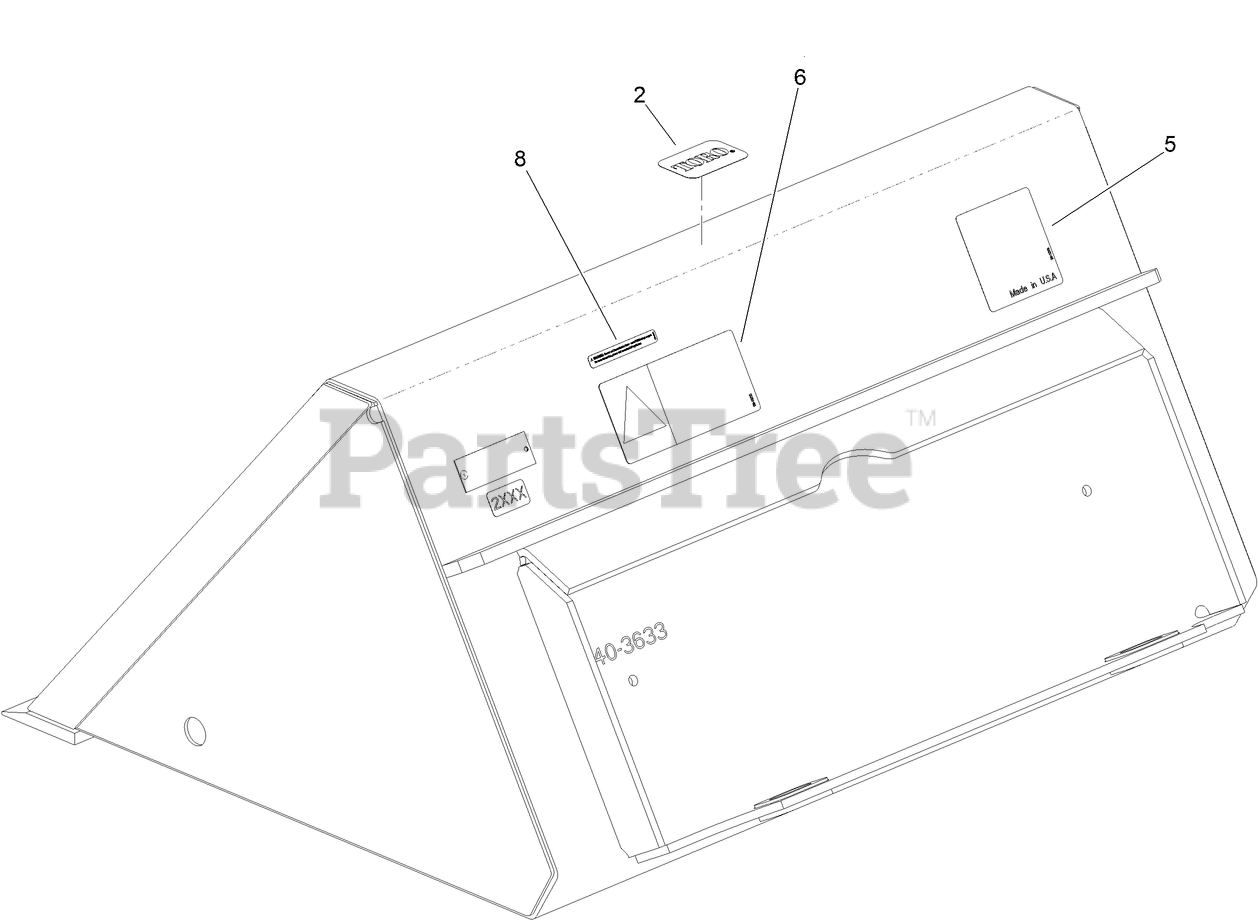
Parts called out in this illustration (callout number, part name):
2	DECAL
5	DECAL
6	DECAL-LOAD RATING
8	DECAL-WARNING
